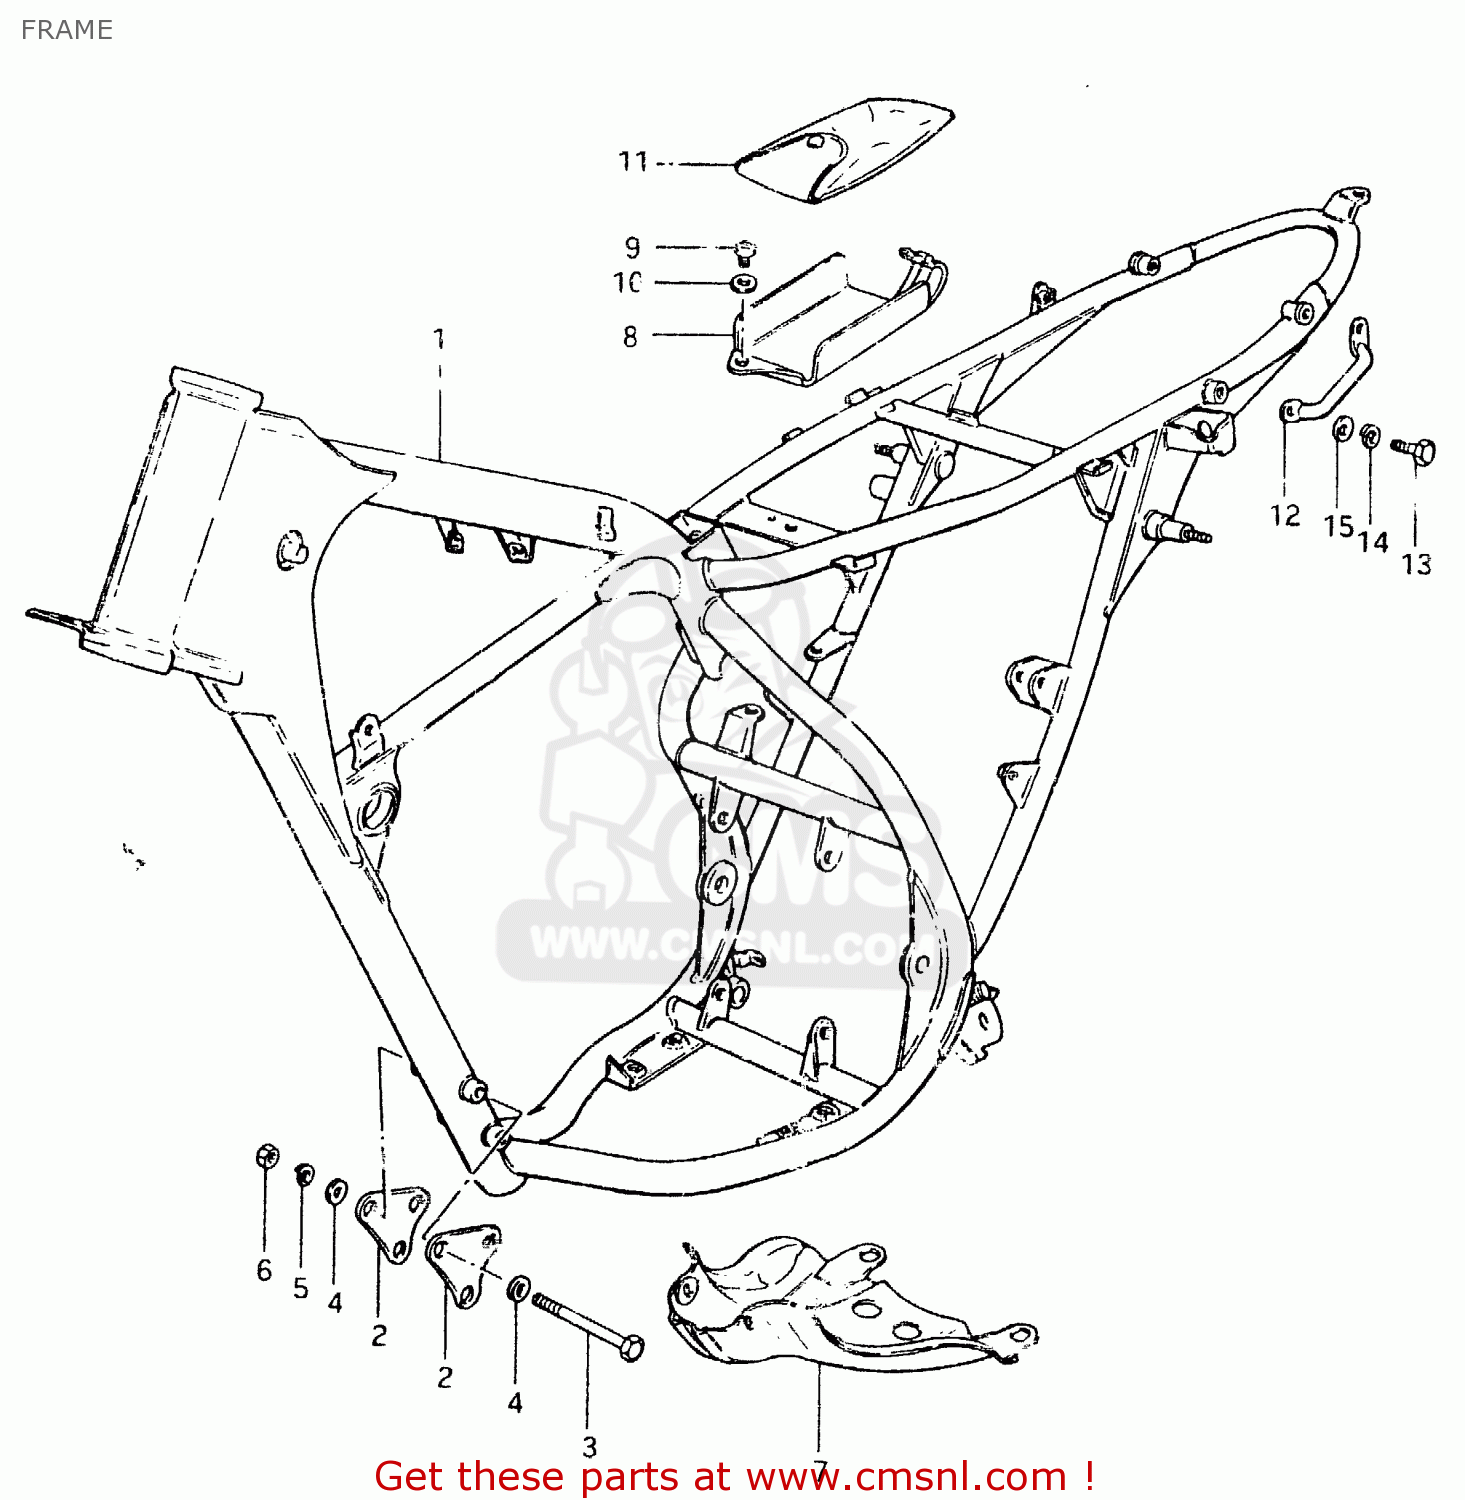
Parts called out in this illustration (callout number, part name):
1	FRAME
2	PLATE,ENG MTG
3	BOLT,8X75
4	WASHER
5	LOCK WASHER
6	NUT
7	PROTECTOR, ENGINE
8	HOLDER,TOOL
9	SCREW
10	WASHER
11	TOOL SET
12	GRIP,FRAME HANDLE
13	BOLT
14	LOCK WASHER
15	WASHER
